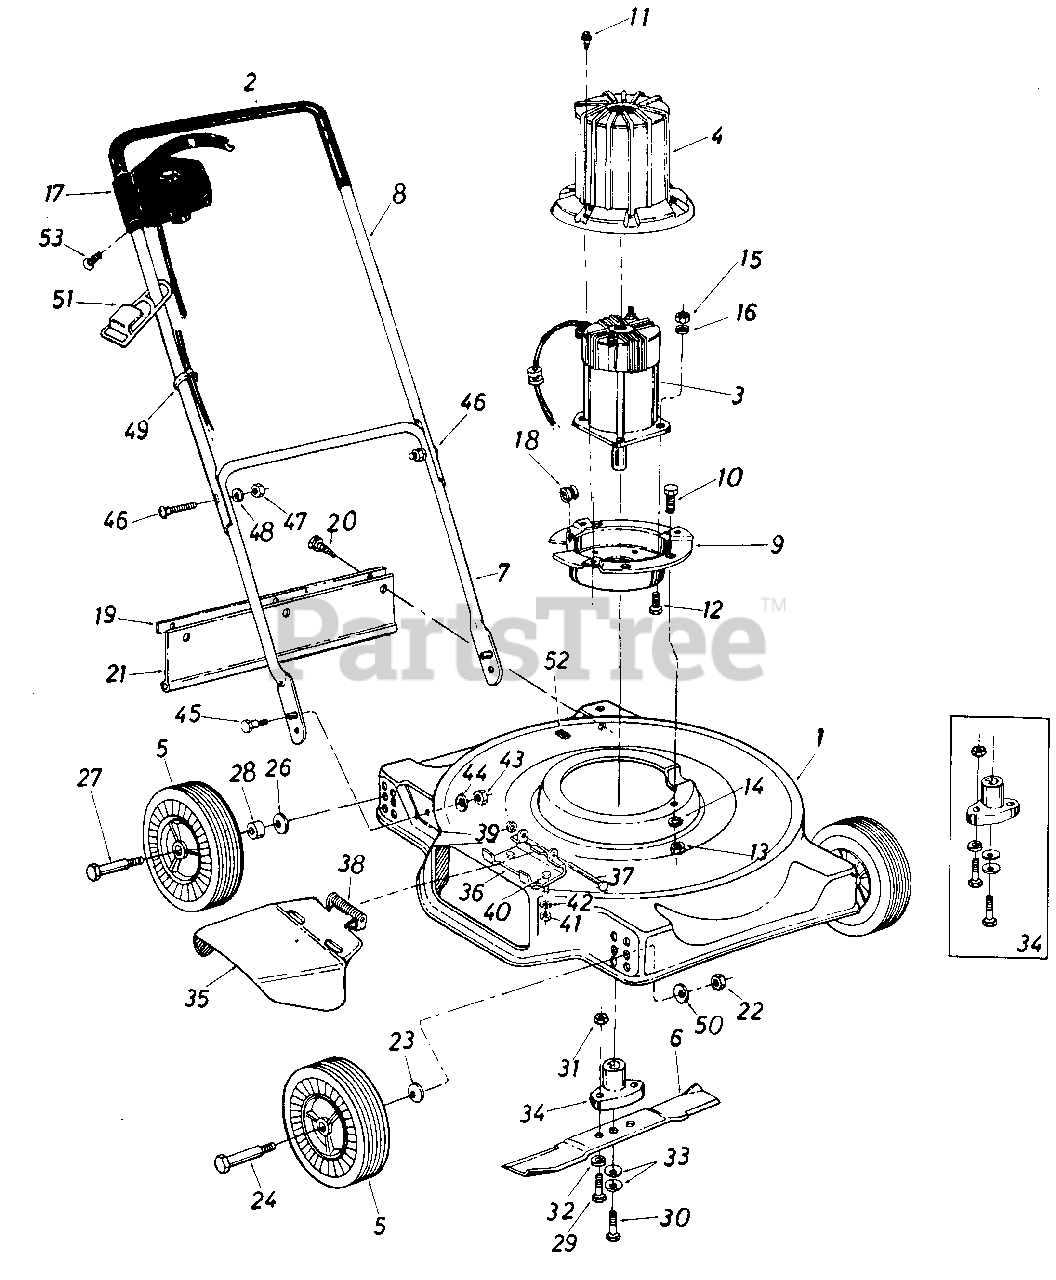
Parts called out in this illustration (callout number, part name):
1	20" Deck Ass'y.
4	Motor Shroud
5	Wheel Ass'y. Comp. 7 x 1.50
6	20" Blade
7	Lower Handle
8	Upper Handle
9	Drive Housing Brkt.-L.H.
10	Hex Bolt 3/8-16 x 1.00" Lg.
11	Hex Wash. Hd. "F" Tap Scr. #10-32 x .314" Lg.
12	Hex Bolt 1/4-20 x 1.00" Lg.*
13	Hex Nut 3/8-16 Thd.
14	L-Wash. 3/8" I.D.
15	Hex Nut 1/4-20 Thd.
16	L-Wash. 1/4" I.D.
17	Control w/Cord
18	Cord Restraint
19	Retaining Strip
20	Hex Wash. Hd. AB-Tap Scr. 1/4 x.62" Lg.
21	Rear Flap Ass'y. 4.65 x 17.2" Lg.
22	Hex Nut 3/8-16 Thd.
23	Bell-Wash. .400" I.D. x .88" O.D.
24	Shld. Bolt .498" Dia. x 1.450" Lg.
26	Bell-Wash. .400" I.D. x .88" O.D.
27	Shld. Bolt .498" Dia. x 1.830" Lg.
28	Spacer .511" I.D. x .70" O.D. x.38" Lg.
29	Hex Bolt 5/16-24 x 1.001' Lg. (Grade 5)
30	Hex Bolt 5/16-24 x .75" Lg.
31	Hex Nut 5/16-24 Thd.*
32	L-Wash. 5/16" I.D.*
33	Bell-Wash. .345" I.D. x .88" O.D.
34	Blade Adapter Kit
35	Chute Deflector Ass'y. Comp.
36	Deflector Hinge Plate
37	Hinge Pin
38	Torsion Spring
39	Push On Flange Nut
40	Hex Bolt 1/4-20 x .50" Lg.*
41	Hex Nut 1/4-20 Thd.*
42	L-Wash. 1/4" I.D.*
43	Hex Nut 5/16-18 Thd.*
44	Bell-Wash. .345" I.D. x .88" O.D.
45	Shld. Bolt .437" Dia. x .268" Lg.
46	Curved Hd. Carr. Bolt 5/16-18 x 1.38" Lg.
47	Hex Nut 5/16-18 Thd.*
48	L-Wash. 5/16" I.D.*
49	Cable Tie
50	Bell-Wash. .39" I.D. x 1.13" O.D.
51	Restraint
52	Plastic Plug
53	Truss Mach. AB-Tap Scr.
